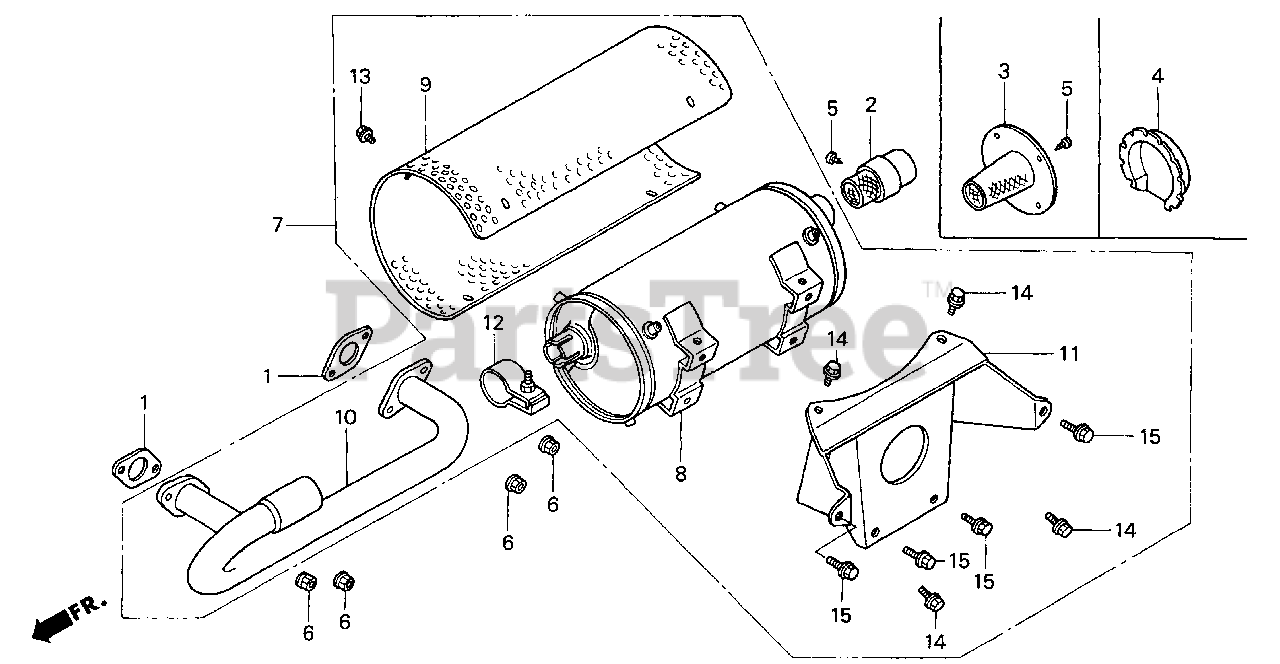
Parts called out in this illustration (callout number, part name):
1	GASKET, EX. PIPE
2	ARRESTER, SPARK
3	ARRESTER, SPARK (SIDE)
4	DEFLECTOR KIT, EX.
5	SCREW (NELSON)
6	NUT, FLANGE (8MM)
